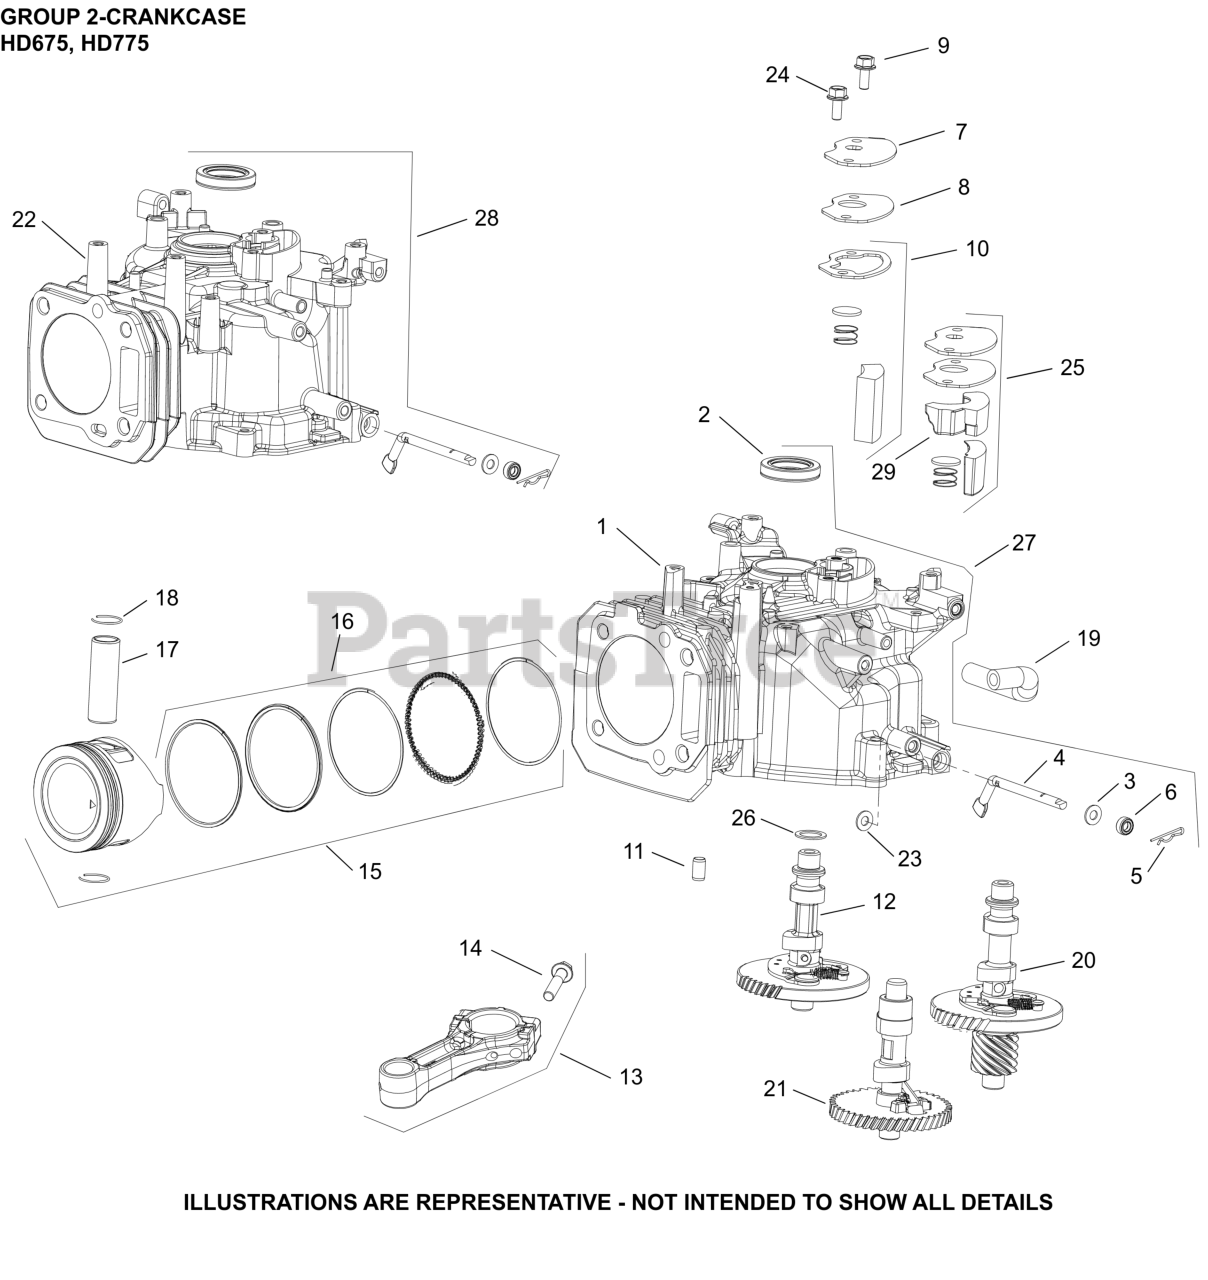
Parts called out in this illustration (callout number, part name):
1	CRANKCASE
2	SEAL, CCASE/FLYWHEEL
4	SHAFT, GOVERNOR CROSS
5	CLIP, GOVERNOR SHAFT
6	SEAL, OIL
7	COVER, BREATHER
8	GASKET, BREATHER COVER
9	SCREW, HEX FLANGE (M6)-USE 25 086 433-S
10	KIT, BREATHER FILTER
11	PIN, DOWEL (8mm)
13	CONNECTING ROD
14	SCREW, HEX FLANGE (M7)
15	KIT, PISTON
17	PIN, PISTON
18	RETAINER, PISTON PIN
19	HOSE, BREATHER
20	CAMSHAFT ASSEMBLY
23	WASHER, FLAT (DIA 13mm O.D.)
25	KIT, BREATHER FILTER
